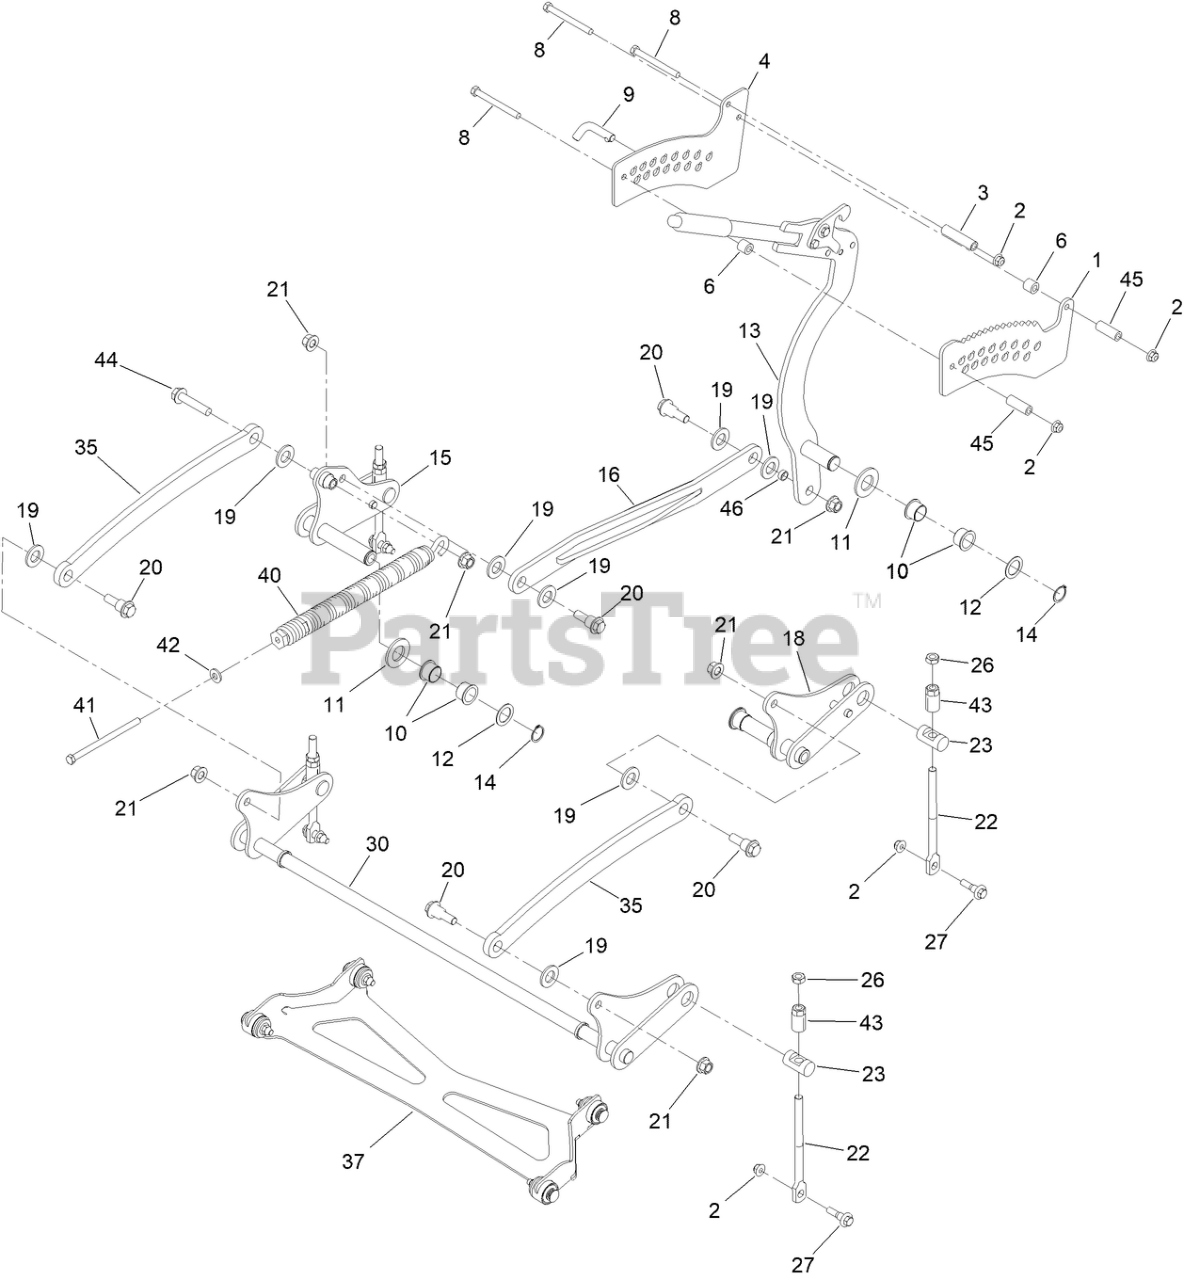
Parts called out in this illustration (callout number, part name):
1	PLATE-HOC, INNER
2	NUT-HF, NI
3	SPACER
4	HOC PLATE AND DECAL ASM
6	SPACER
8	SCREW-HHF
9	PIN-HOC
10	BUSHING
11	WASHER-FLAT
12	WASHER-THRUST
13	HOC LEVER ASM
14	RING-RETAINING
15	RH REAR LIFT ARM ASM [BLACK]
16	HOC LINK ASM [BLACK]
18	LH REAR LIFT ARM ASM [BLACK]
19	WASHER-FLAT
20	SCREW-SHOULDER, HHF
21	NUT-LOCK
22	LINK-ADJUSTER, DECK LIFT
23	TRUNNION
26	NUT-JAM
27	BOLT-SHOULDER
30	FRONT CROSS SHAFT ASM [BLACK]
35	LINK-LIFT
37	ASM-DECK STRUT W/BUSHINGS
40	SPRING-EXTENSION
41	BOLT-TAP, HH
42	WASHER-BELLEVILLE
43	ADJUSTER-LIFT, DECK
44	SCREW-HHF
45	SPACER
46	SPACER
